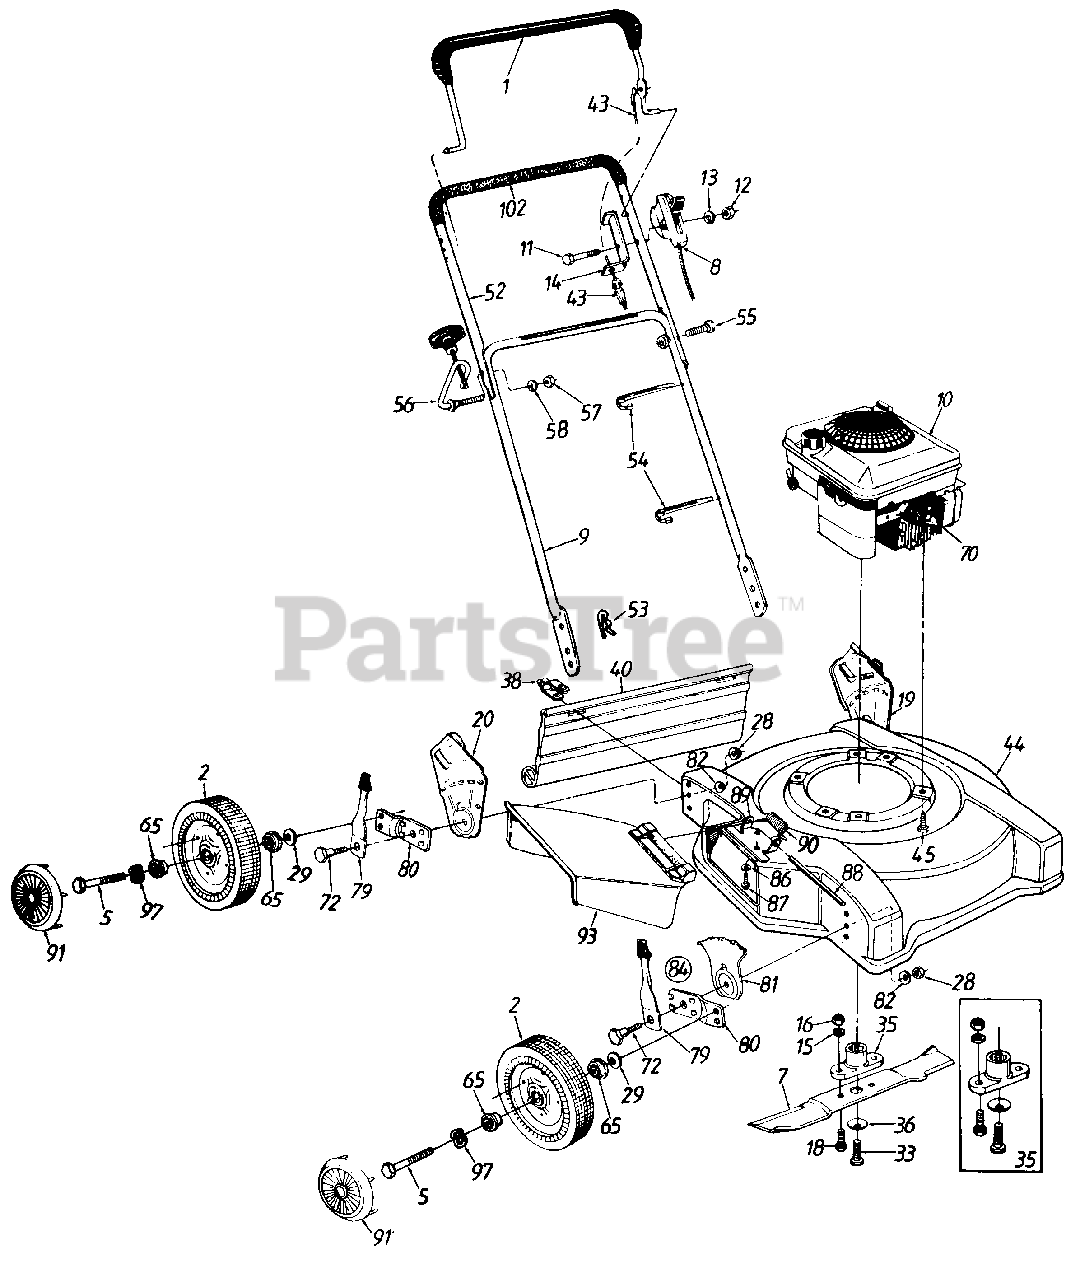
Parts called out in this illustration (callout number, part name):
1	Control Handle
2	Wheel Ass'y. Comp.
5	Axle Bolt
7	20" Blade
8	Throttle Control Ass'y. Comp. 49.6
9	Lower Handle
10	Engine
11	Hex Bolt 1/4-20 x 2" Lg.
12	Hex Nut 1/4-20 Thd.
13	Spr. Wash. .265" I.D. x .562"
14	Cable Mtg. Bracket
15	L-Wash. 3/8" I.D.
16	Hex Nut 3/8-24 Thd.
18	Hex Bolt 3/8-24 x 1.0" Lg.
19	Wheel Brkt. Ass'y. L.H.
20	Wheel Brkt. Ass'y. R.H.
28	Hex Nut 3/8-16 Thd.
29	Bell-Wash. .400" I.D. x .88"
33	Hex Bolt 7/16-20 x 1.5" Lg.
35	Blade Adapter Kit
36	Bell-Wash. .46" I.D.
38	Hinge Clip
40	Rear Flap Ass'y.
43	Control Cable 36"
44	20" Deck Ass'y.
45	Hex Wash. Hd. TT-Tap Scr. 3/8-16 x 1.00" Lg.
52	Upper Handle
53	Intern. Cot. Pin 5/16" Dia.
54	Cable Tie
55	Cuved Carriage Bolt 5/16-18 x 1.38" Lg.
56	Rope Guide Bolt
57	Hex Nut 5/16-18 Thd .
58	L-Wash. 5/16" I.D.
65	Ball Bearing 1/2" I.D.
70	Spark Plug Boot
72	Shoulder Bolt .50" Dia.
79	Spring Lever Ass'y. w/Knob
81	Height Adj. Plate
82	Bell-Wash. .39" I.D. x 1.38"
84	Front Height Adj. Ass'y. Comp. R.H.
86	Bell-Wash. .285" I.D. x 75" O.D.
87	Hex Wash. Hd. Tap Scr. 1/4-20 x 5" Lg.
88	Hinge Pin
89	Adapter Plate
90	Torsion Spring
91	Hub Cap
93	Chute Deflector Ass'y. Comp.
97	Wave Washer 53" I.D.
102	Foam Grip
